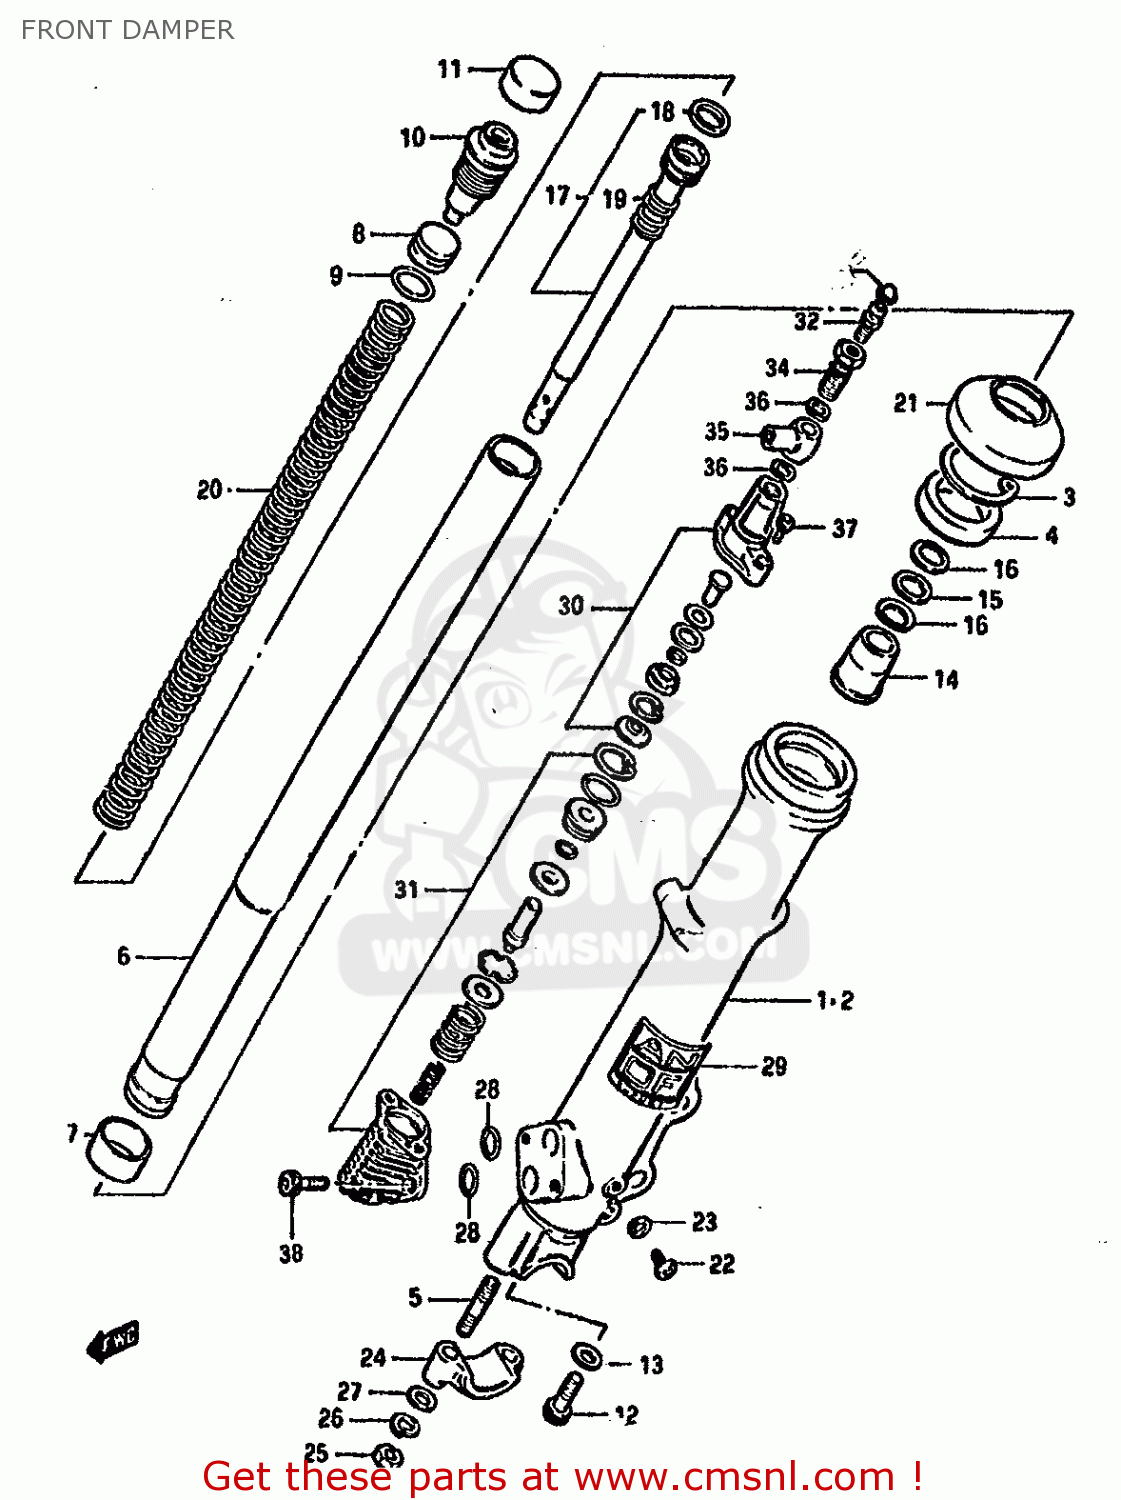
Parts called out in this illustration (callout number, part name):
1	OUTER TUBE, RH
2	OUTER TUBE, LH
3	RING,STOPPER
4	OIL SEAL,FRONT FORK
5	STUD 8X30
6	TUBE,INNER
7	PISTON
8	PISTON,FREE
9	O-RING
10	CAP
11	CAP,RUBBER
12	BOLT,FORK CYLINDER(10X25)
13	GASKET (NAS)
14	PIECE,OIL LOCK
15	WASHER
16	SPRING,LEAF
17	CYLINDER,FRONT FORK
18	RING,PISTON
19	SPRING,REBOUND
20	SPRING,FRONT FORK
21	SEAL,DUST
22	SCREW
23	GASKET,DRAIN,PLUG (NAS)
24	HOLDER,AXLE
25	NUT (8MM)
26	LOCK WASHER
27	WASHER
28	O RING
29	LABEL
30	MODULATOR PLANGER SET
31	MODULATOR VALVE SET
32	BREATHER,AIR
33	CAP,BREADER
34	BOLT,UNION
35	SPACER,FRONT FORK MODULATOR
36	WASHER
37	BOLT,FR FORK
38	BOLT,FRONT FORK
